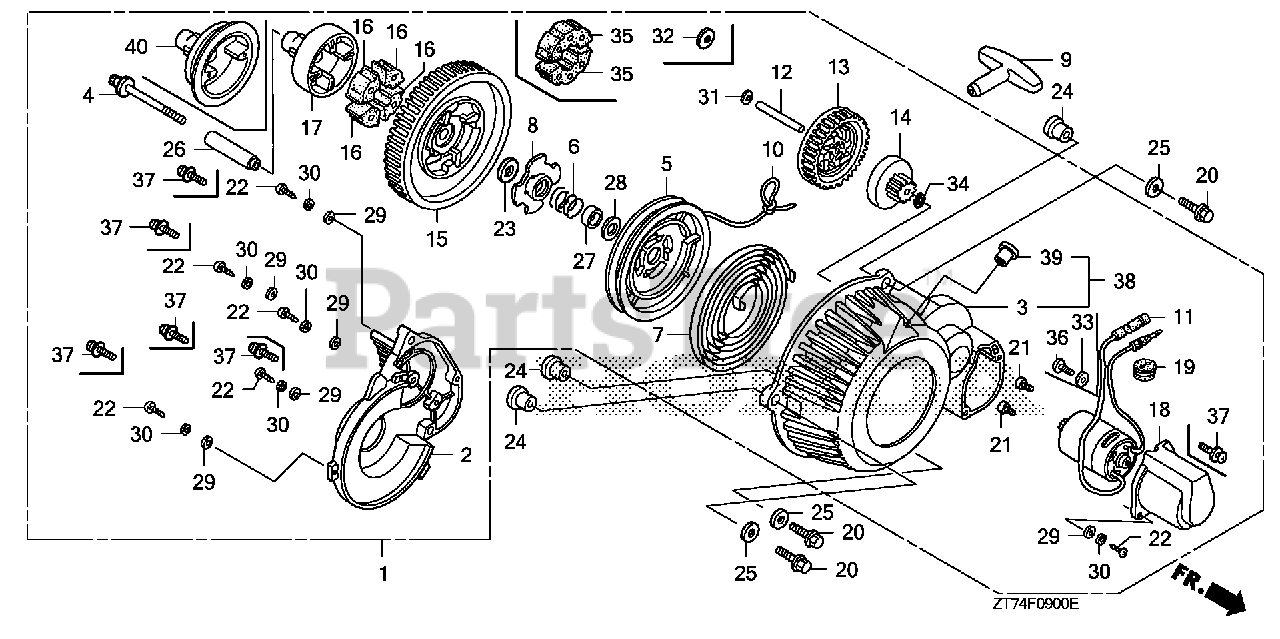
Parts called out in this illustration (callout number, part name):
1	STARTER ASSY., STARTER MOTOR & RECOIL (NA USE ALT:06284-ZS9-305)
1	STARTER ASSY., STARTER MOTOR & RECOIL
2	COVER, GEAR
3	CASE, RECOIL STARTER (NOT AVAILABLE)
3	CASE, RECOIL STARTER
4	BOLT, CENTER (8MM)
5	REEL, RECOIL STARTER
6	SPRING, FRICTION
7	SPRING, RECOIL STARTER
8	GUIDE, RATCHET
9	KNOB, RECOIL STARTER
10	ROPE, RECOIL STARTER
11	STARTER MOTOR SET (D.C.) (NOT AVAILABLE)
11	STARTER MOTOR SET (D.C.)
12	SHAFT, GEAR
13	GEAR (B) (NOT AVAILABLE)
13	GEAR (B)
14	GEAR (C)
14	GEAR (C) (NOT AVAILABLE)
15	GEAR (F)
15	GEAR (F) (NOT AVAILABLE)
16	DAMPER
17	CAM, DRIVE
17	CAM, DRIVE (NOT AVAILABLE)
18	COVER, MOTOR
20	BOLT, FLANGE (6X23)
21	SCREW, CAP (3X8)
22	SCREW (4X16)
23	WASHER C (11MM)
24	COLLAR, RECOIL STARTER
25	WASHER, BLACK (20MM)
26	COLLAR (1.8X51.4)
27	COLLAR (2.15X9.4)
28	WASHER B (16MM)
29	WASHER A (4MM)
30	WASHER, SPRING (4MM) (NOT AVAILABLE)
31	WASHER E (6MM)
32	WASHER (8MM)
33	WASHER (3.4MM)
34	WASHER E (6MM)
35	DAMPER
36	SCREW (3X8)
37	SCREW-WASHER (4X16)
